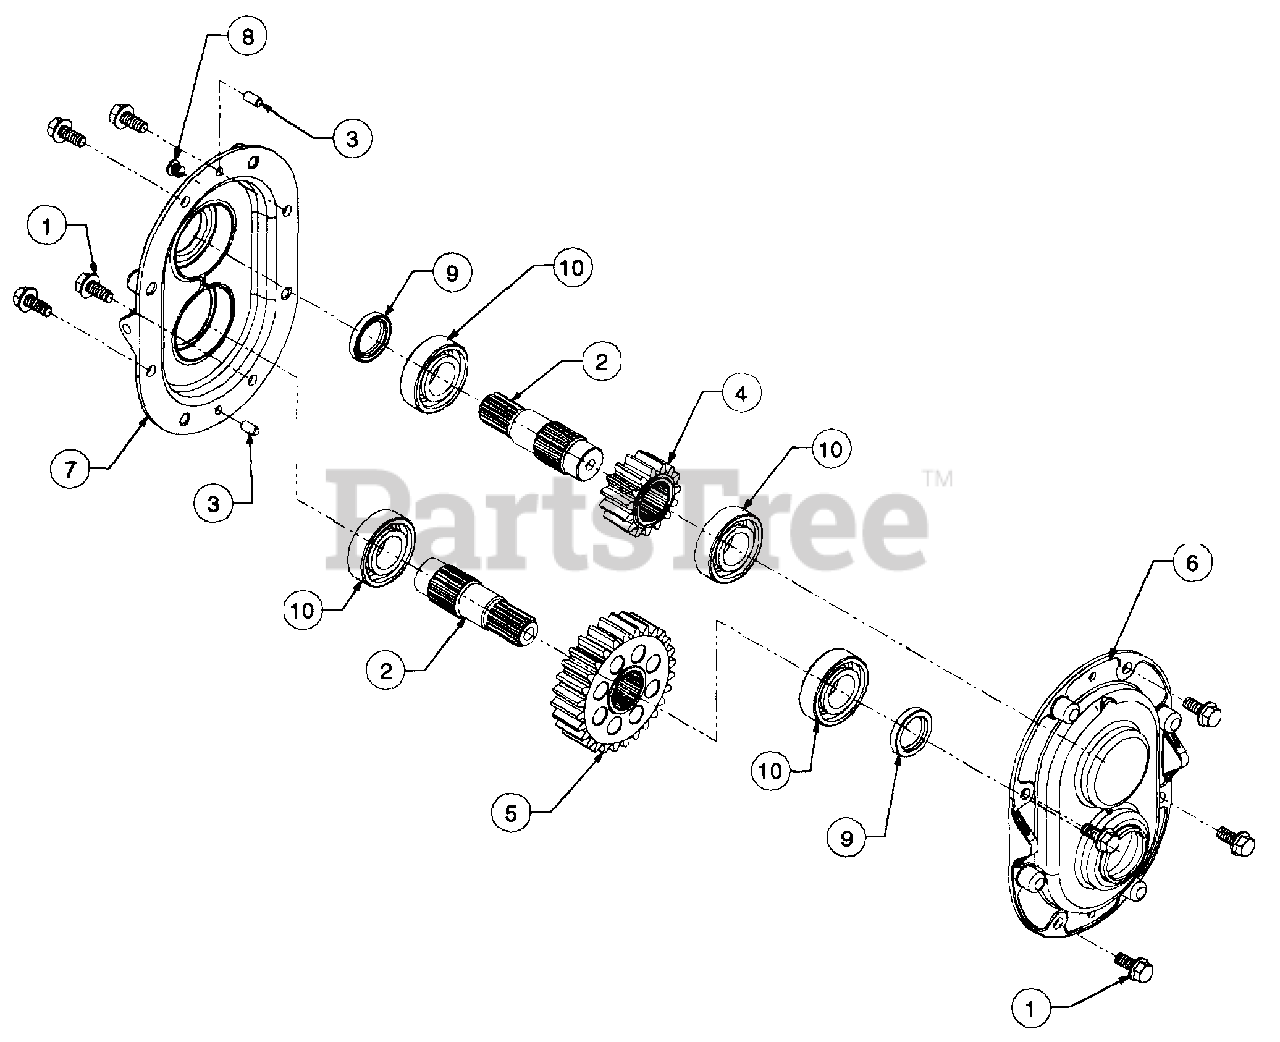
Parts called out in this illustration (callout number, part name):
1	Screw, Hex Wash. Hd. Tapp 5/16-18 X .75
2	Shaft, Input/Output
3	Pin, Dowel, 1/4 X 1/2
4	Spur Gear, 28T
5	Spur Gear, 15T
6	Housing Half - Front
7	Housing Half - Rear w/mtng. & plug holes
8	Plug, 1/4 X .437
9	Seal, Oil, 25mm X 32mm X 6mm
10	Bearing, Ball
